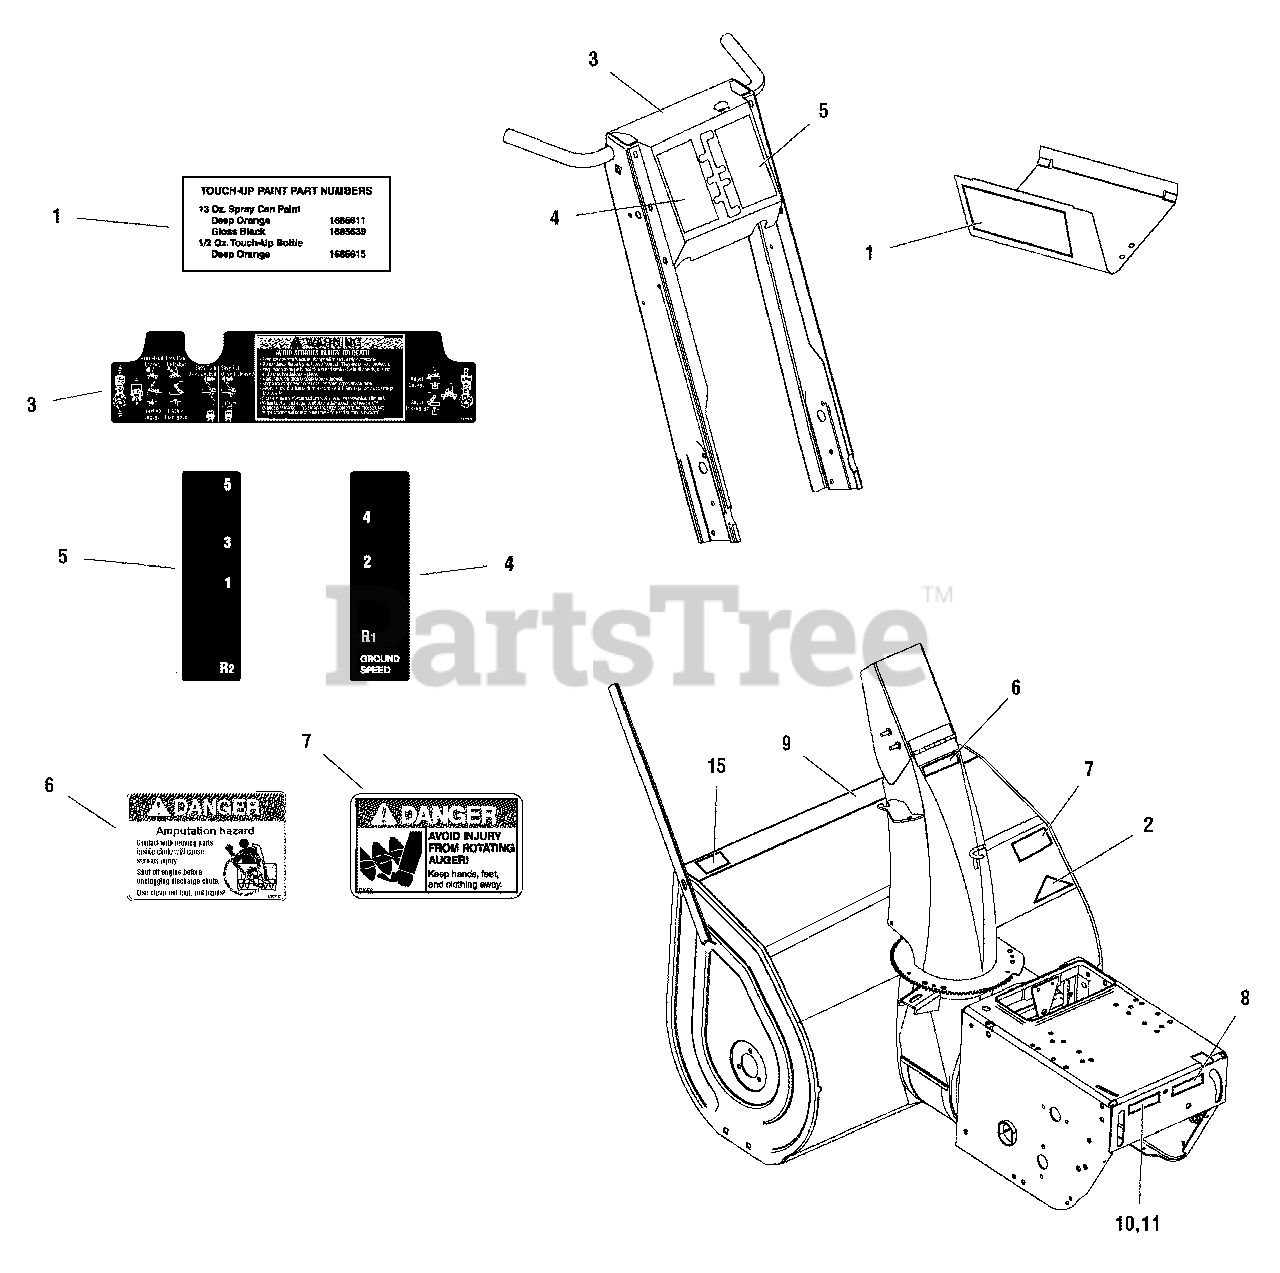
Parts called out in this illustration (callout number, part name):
1	DECAL, Touch Up Paint, Orange, Black, Red
3	DECAL, Dashboard EZ Turn Channel Handles
4	DECAL, 4 2 R1 Ground Speed R.H.
5	DECAL, 5 3 R2 Shift Pattern, L.H.
6	DECAL, Danger Amputation Hazard
7	DECAL, Danger Avoid Injury from Auger
8	DECAL, Patent Snowthrower
9	DECAL, Simplicity Stripe 24" Long
9	DECAL, Simplicity Stripe 28" Long
9	DECAL, Simplicity Stripe 32" Long
9	DECAL, Simplicity Stripe 38" Long
15	DECAL, Signature Pro 10524P
15	DECAL, Signature Pro 11528P
15	DECAL, Signature Pro 1332P
15	DECAL, Signature Pro 1338P
